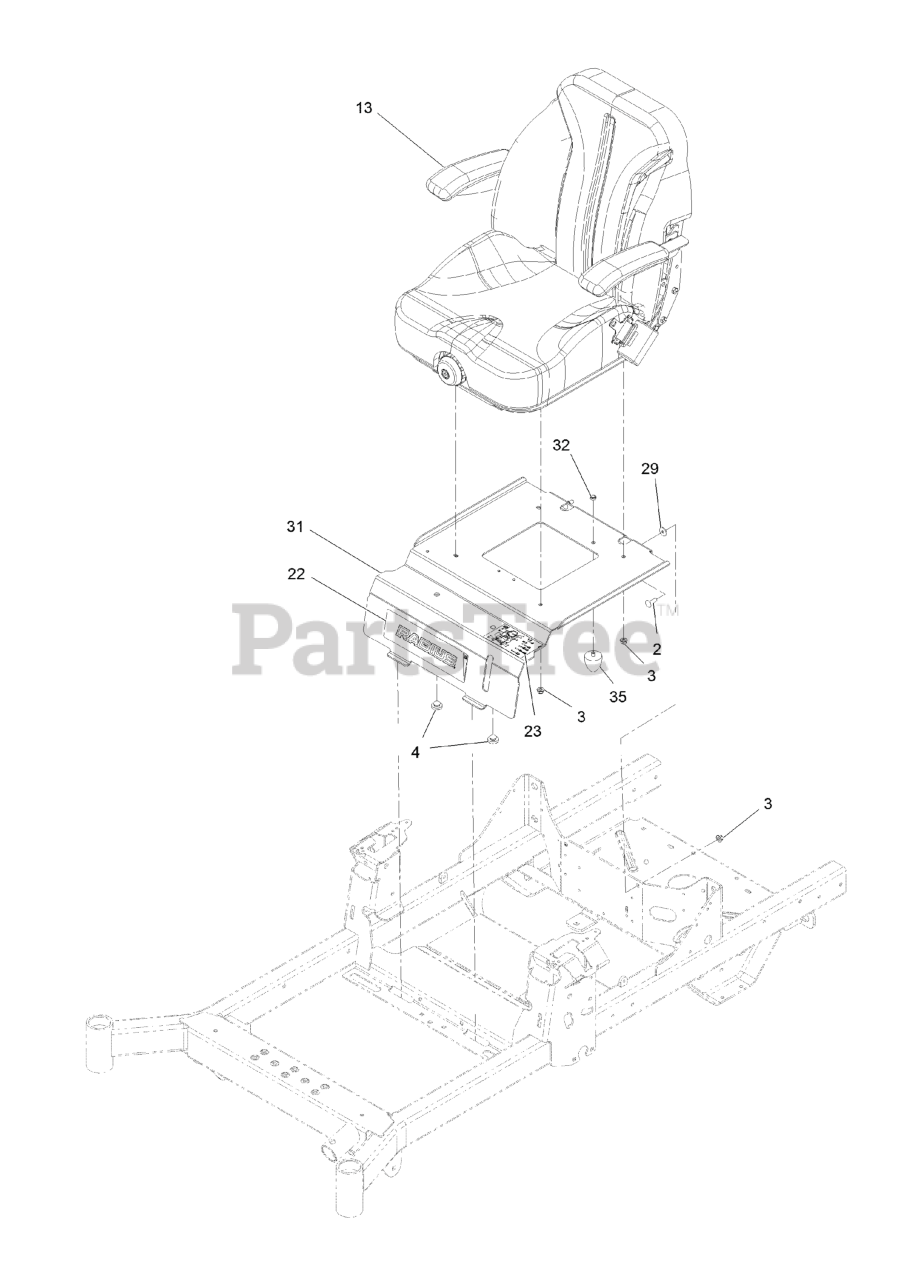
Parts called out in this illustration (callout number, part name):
2	SCREW-CARR
3	NUT-HF, NI
4	BUMPER-SEAT
13	ASM-SUSP SEAT
22	DECAL-RADIUS LOGO
23	DECAL-AID, SERVICE
31	PLATE-FIXED SEAT
32	NUT-LOCK, NI
35	BUMPER-RUBBER
